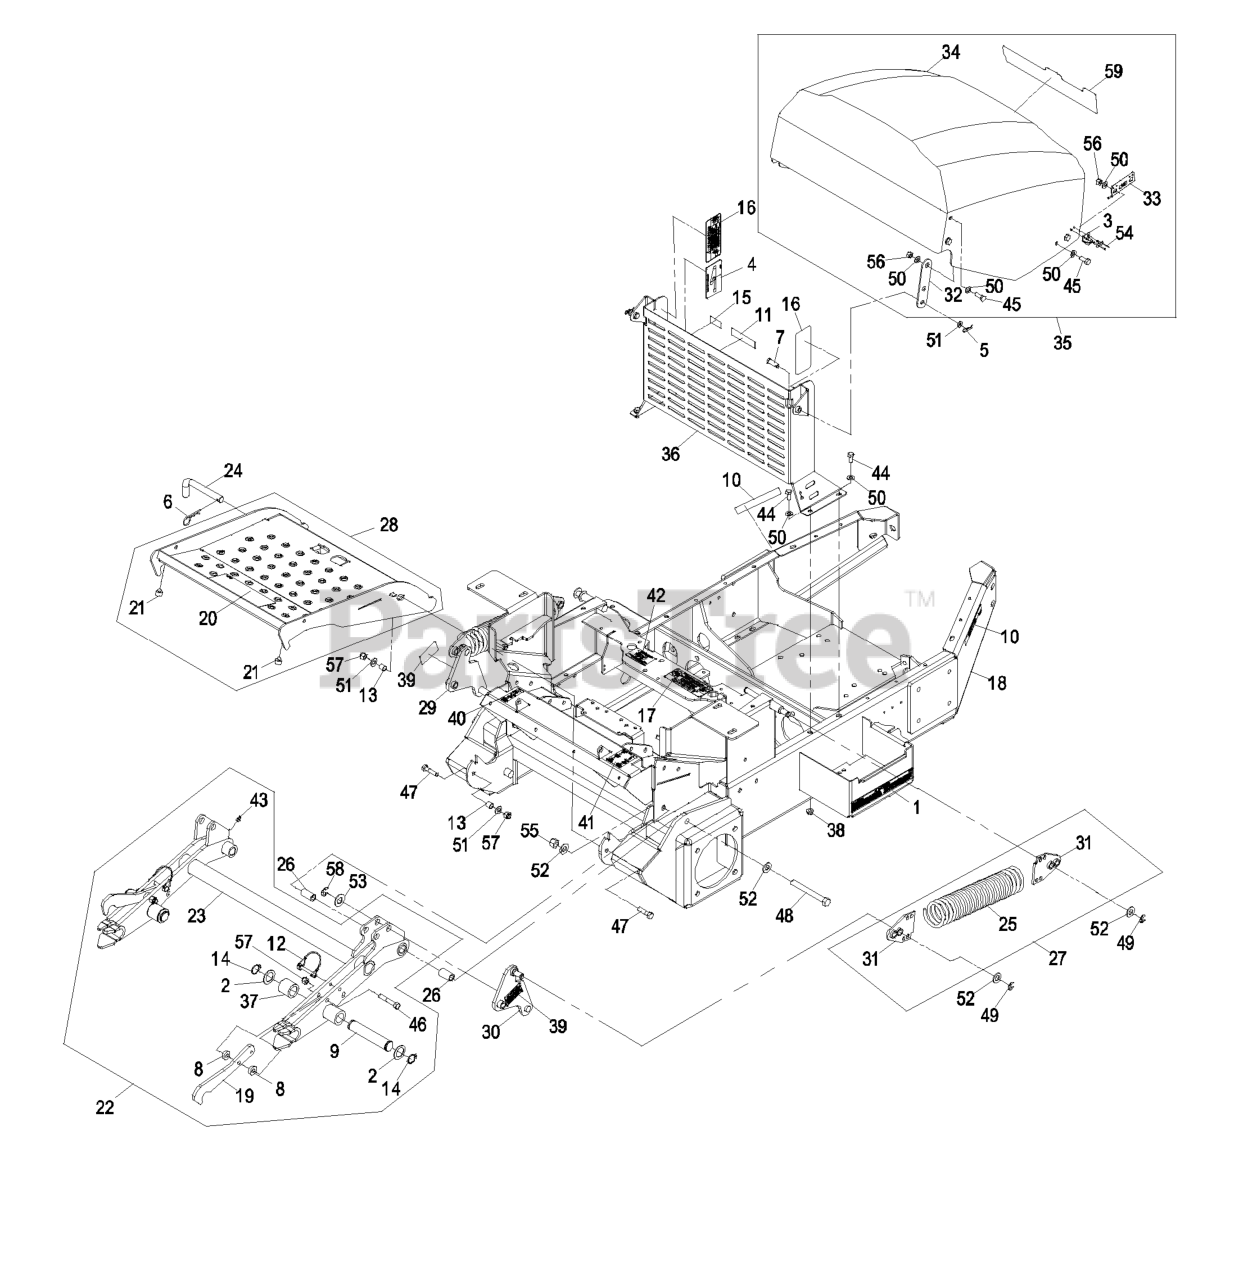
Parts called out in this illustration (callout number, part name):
1	DECAL-BATTERY
2	WASHER-SPACER
4	DECAL-ROUTING, BELT
5	PIN-COTTER
6	PIN-COTTER
7	PIN-CLEVIS
8	SPACER
10	DECAL-WARNING
11	DECAL-COVER, MISSING
12	PIN-HITCH
13	SPACER-TUBE, PUMP LINK
14	RING-RETAINING
16	DECAL-DEVICES, ROTATING
17	DECAL,PUMP FAN WARNING
18	ASM, MAIN FRAME FMZ A/C
19	LATCH, FMZ HITCH (PLATED)
20	DECAL-WARNING
21	BUMPER-RUBBER
22	ASM,HITCH FMZ
24	PIN,FULL FOLD (PLTD)
25	SPRING,EXTENSION (PLATED)
26	BUSHING,HITCH PIVOT
27	ASM,FMZ WT XFR SPRING
29	ASM,FMZ RH SPRING BELLCRA
30	ASM,FMZ LH SPRING BELLCRA
31	WLD,FMZ SPRING ANCHOR (PL
33	HOOK, HOOD
34	DECAL,FRONTRUNNER
35	ASM,FMZ AC HOOD W/DCL COM
36	ASM,FMZ A/C HOOD SUPPORT
37	ROLLER,LOCK LEVER
39	DECAL,SPRING LOADED
40	DECAL-CONTROL, MOTION
41	DECAL,MOTION CNTL/PARK BR
42	DECAL,PUMP DRIVE RELEASE
43	FITTING-GREASE
44	SCREW-HH
45	SCREW-HH
46	SCREW-HH
47	SCREW-HH
48	SCREW-HH
49	RING-RETAINING, EXTERNAL
50	WASHER-PLAIN
51	WASHER-FLAT
52	WASHER-FLAT
53	WASHER-FLAT
55	NUT-LOCK, NI
56	NUT-LOCK, NI
57	NUT-LOCK, NI
59	DECAL,FRONTRUNNER
